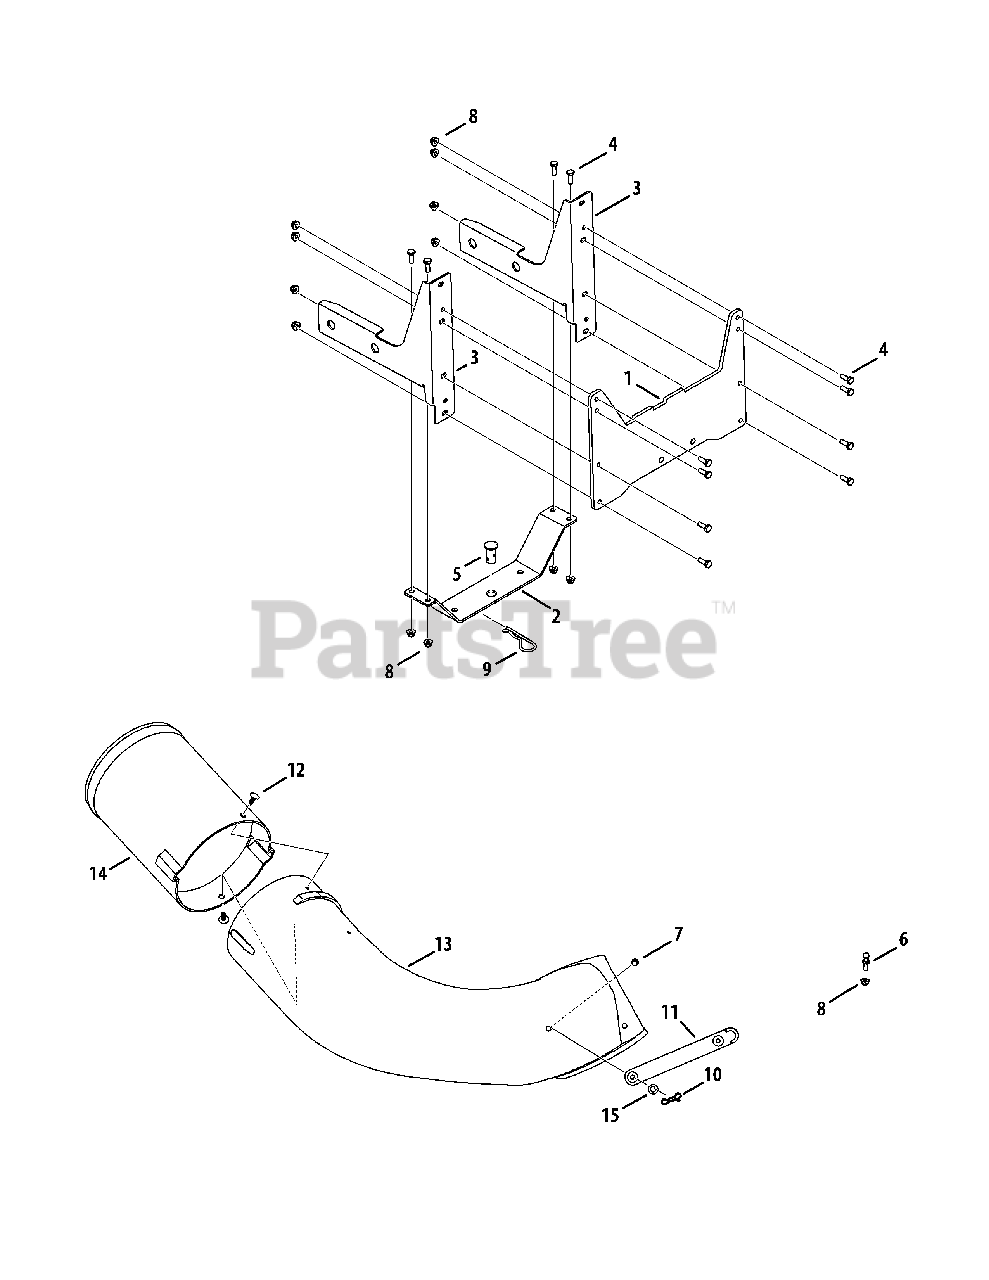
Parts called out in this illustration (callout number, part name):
1	Bagger Mounting Plate
3	Catcher Support Bracket
4	Hex Head Screw, 1/4-20 x .75
5	Clevis Pin, .62" Dia.
6	Grass-catcher Pin, 1/4-20
7	Clevis Pin, 5/16 x .75 Lg.
8	Flange Lock Nut, 1/4-20
9	Internal Cotter Pin, .148 x 3.00
10	Bow-Tie Cotter Pin, 72
11	Chute Strap, 6.00 Lg.
12	Ratchet Clip
13	Bagger Discharge Chute, Elbow 38/42" Deck
14	Bagger Chute Adapter
15	Flat Washer, .344 x .62 x .033
